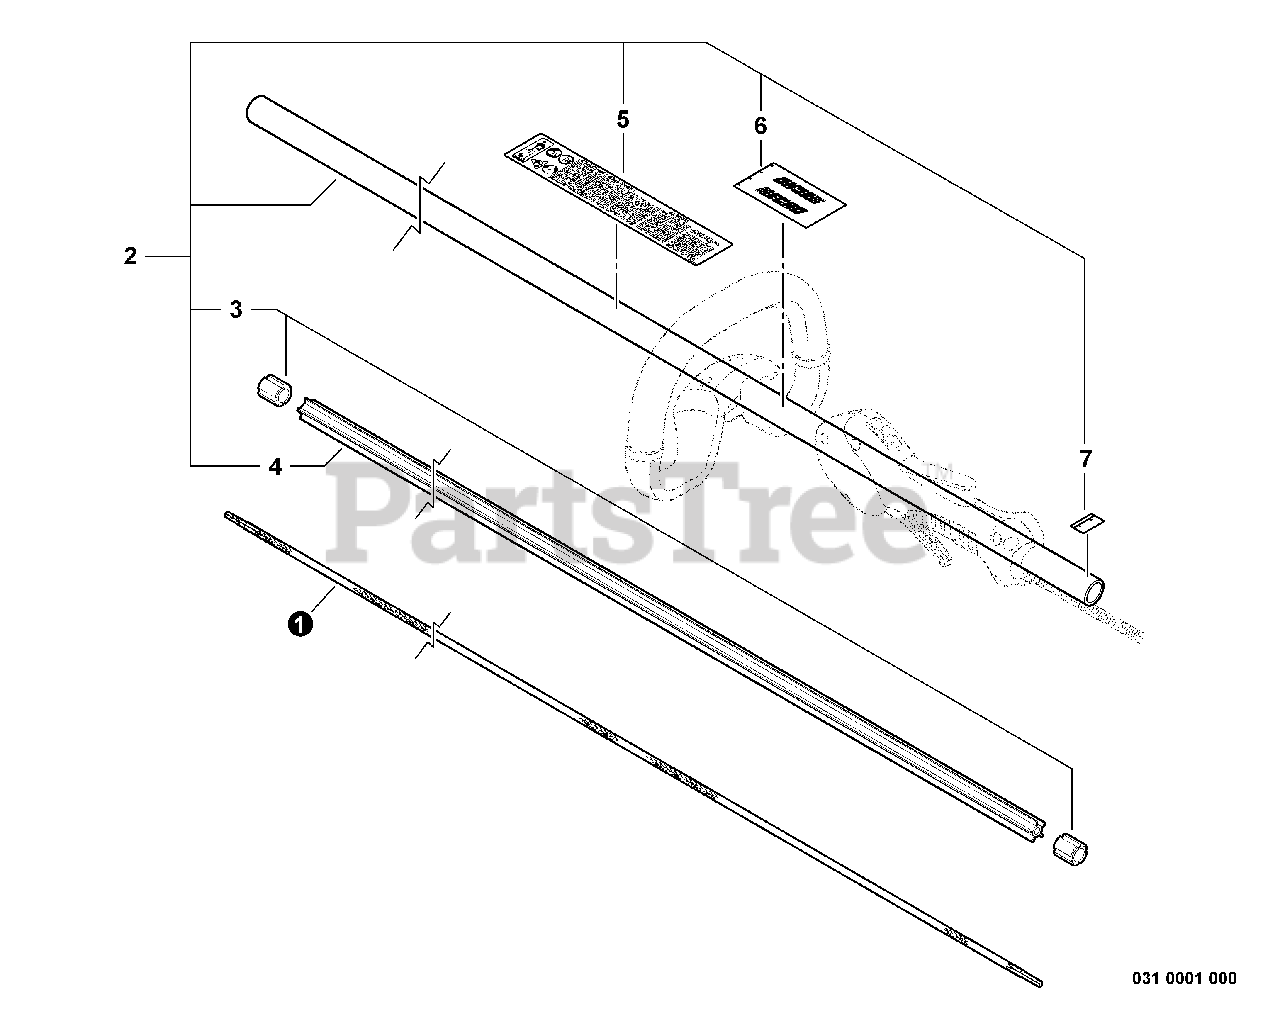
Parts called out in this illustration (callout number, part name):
1	DRIVESHAFT - FLEXIBLE
2	MAIN PIPE ASSY
4	LINER - FLEXIBLE
5	LABEL - CAUTION -- SPANISH
6	LABEL - HANDLE LOCATION
7	LABEL - ALIGNMENT
